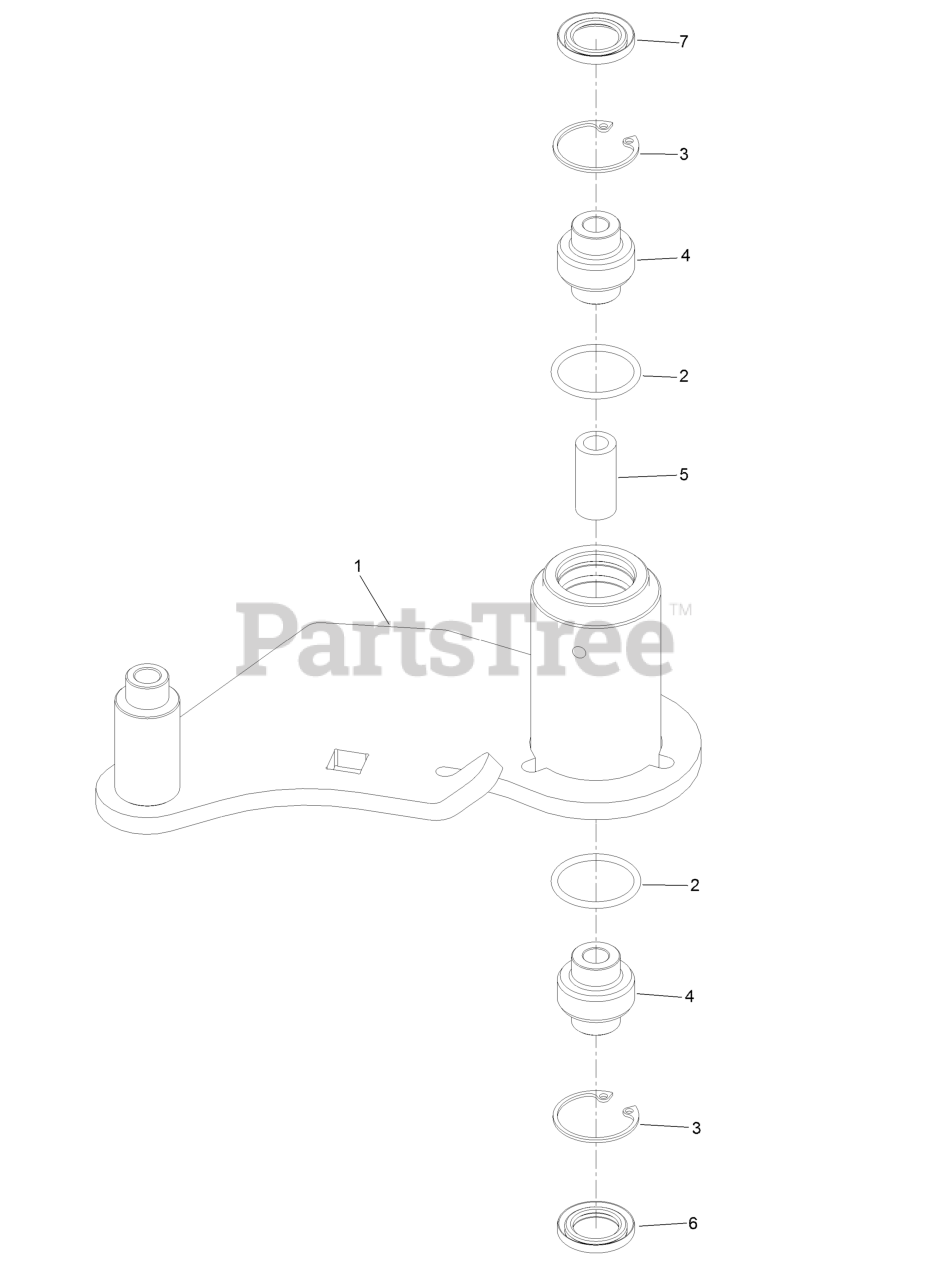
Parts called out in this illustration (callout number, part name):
1	Idler-Deck
3	Ring-Snap
4	Bearing-Spherical
6	Seal-Lip, Double
7	Seal-Lip, Single
